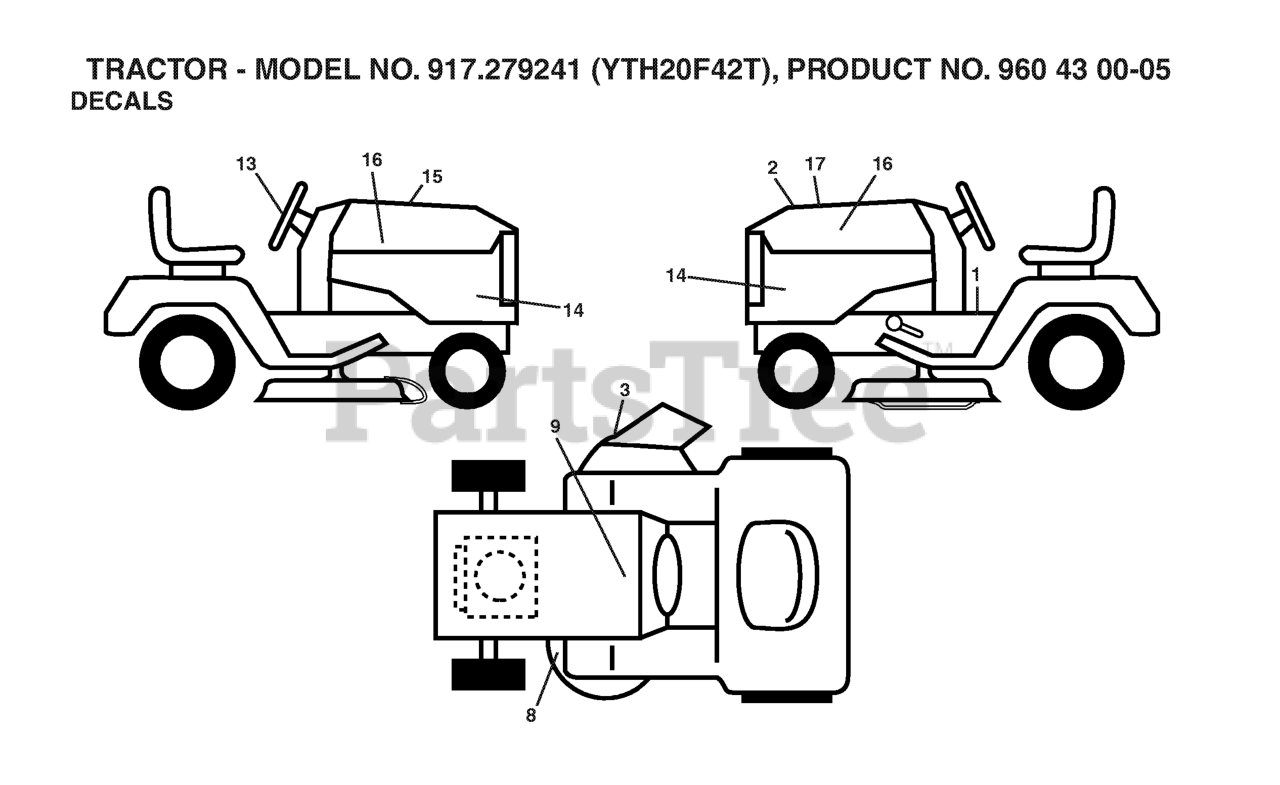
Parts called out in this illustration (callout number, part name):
1	DECAL.FENDER.OPER.TEX.
2	DECAL.HOOD.TOP.INSERT.
3	DECAL.WARN.KEEP.HAND.AWAY
8	DECAL V BELT SCHEMATIC
9	DECAL BTRY SYMBOLS
13	DECAL.WHEEL.STRG.LGN.H
14	DECAL.PANEL.SIDE.YTH20F42T
15	DECAL HOOD CUST. RESP.
16	DECAL.HOOD.LOGO.PLAQUE
17	DECAL.RPL.KH.20.TGB.42
